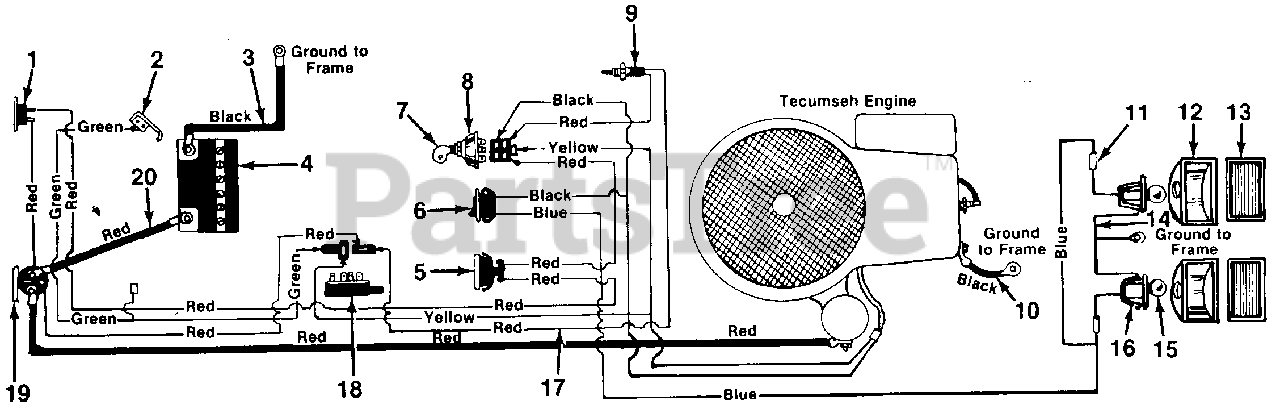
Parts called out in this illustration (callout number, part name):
1	Circuit Breaker
2	Spring Switch
3	Ground Wire
4	12 Volt Battery
5	Ammeter
6	Light Switch
7	Ignition Key
8	Ignition Switch
9	Safety Switch
10	Ground Wire 7.25" Lg. (Black-Engine)
11	Tab Receptacle
12	Headlight Housing
13	Lens
14	Ground Wire
15	Lam p
16	Lamp Socket
17	Wire Harness
18	Safety Switch
19	Solenoid
20	Electric Wire
